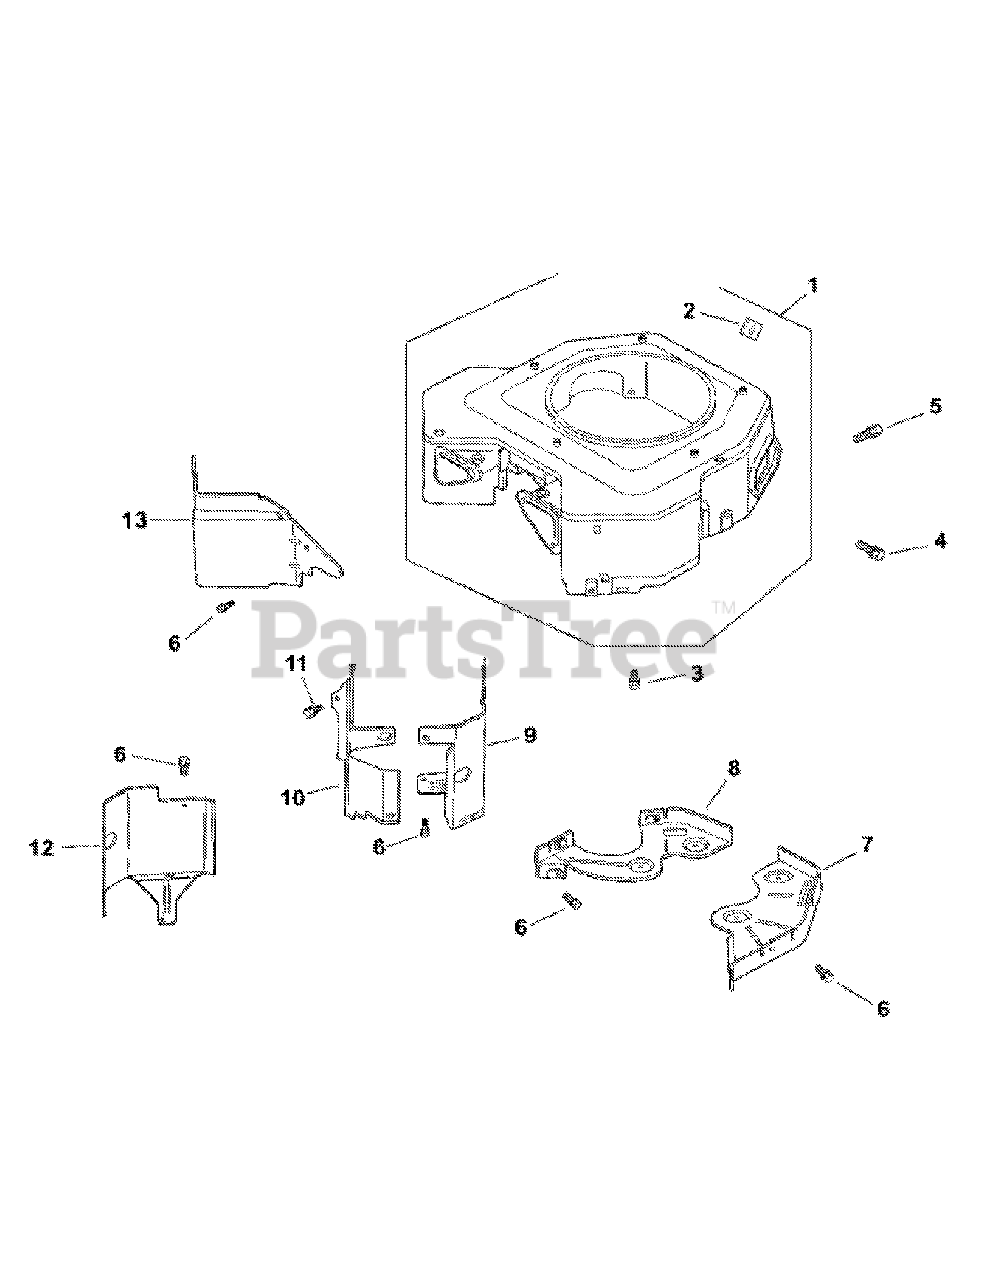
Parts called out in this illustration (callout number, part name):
1	Blower Housing
3	Hex Flange Screw
4	Hex Flange Screw
5	Hex Flange Screw
6	Hex Flange Screw
7	Backing Plate #2 Side
8	Backing Plate #1 Side
9	Cylinder Barrel Baffle #2 Side
10	Valley Baffle #1 Side
11	Hex Flange Screw
12	Cylinder Barrel Baffle #1 Side
13	Valley Baffle #2 Side
